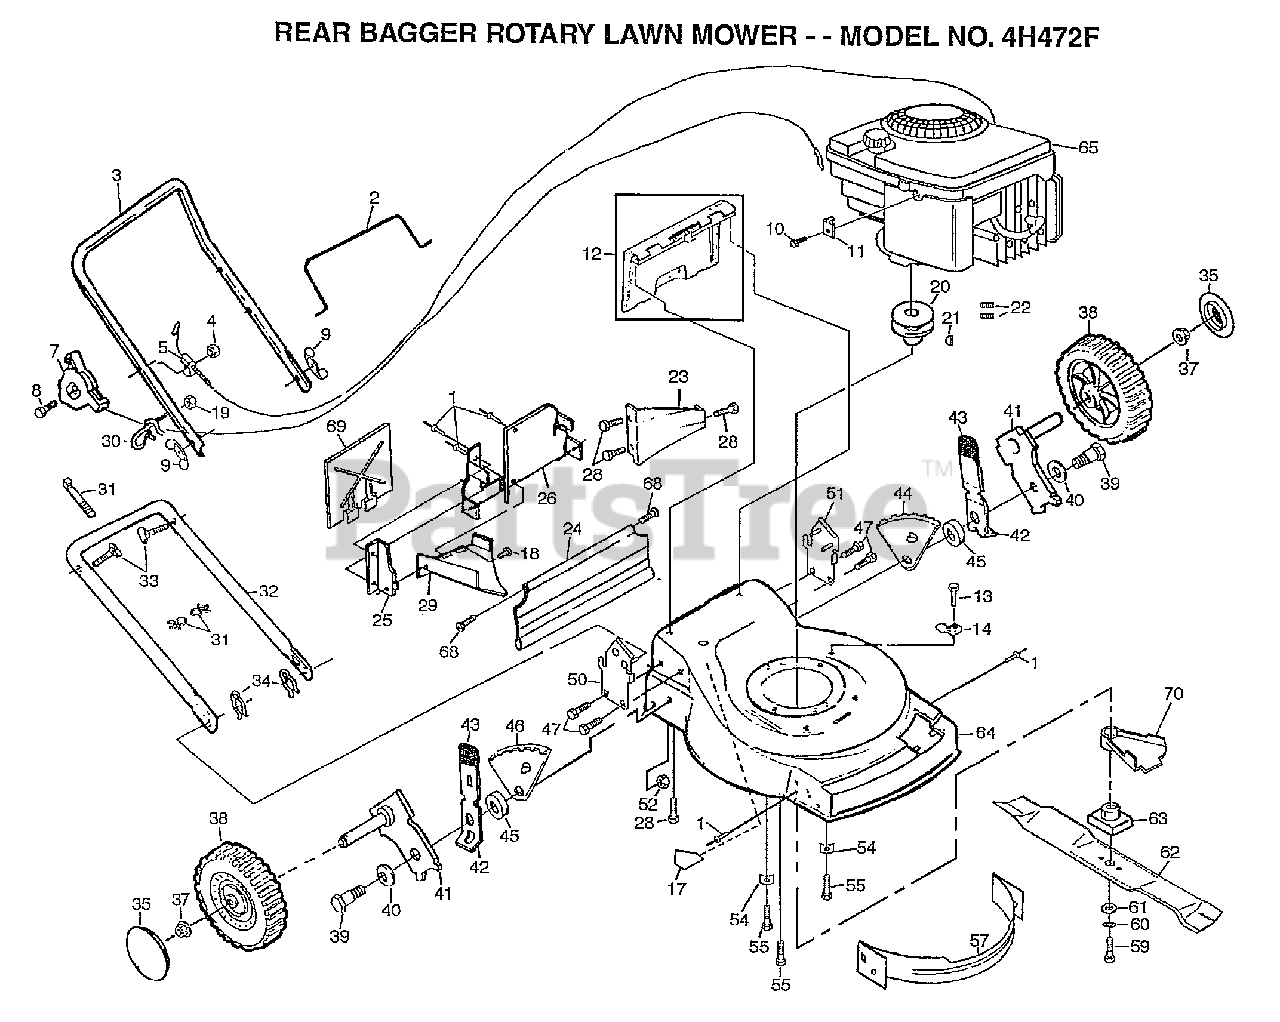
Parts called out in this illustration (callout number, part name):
1	BLIND RIVET
2	BAIL.CNTRL.DLX.ST
5	"CABLE,ENG ZONE CO"
7	"CONTROL, THROTTLE"
8	SCREW.HXHD.WASH.
9	"NUT,WING PM"
10	SCREW PM
11	CABLE CLAMP
12	KIT.DOOR.REAR
13	TAPPING SCREW
14	GUIDE CLIP PM
17	DECAL HYT
18	SCREW.HXTAP.10-24
19	NUT
20	ENGINE.PULLEY.FWG
21	HI PRO KEY PM
22	SCREW
23	REAR BAFFLE
24	SKIRT.REAR.FGD.22
26	PLATE.BACK
28	SCREW
29	DISCHARGE BAFFLE
30	ROPE GUIDE
32	LOWER HANDLE
33	BOLT.HANDLE.LM
34	HAIRPIN COTTER
35	HUB CAP
37	HEX FLANGE LOCKNT
38	WHEEL.8X2.PR.RAD.
39	BOLT SHLD 3/8-16
40	"WASHER, BELLEVIL."
41	ARM.AXLE.ASM.BZP.
42	SPRING SELECTOR
43	KNOB PM
44	BRACKET.ADJ.9.LH
45	SPACER.HEIGHT.ADJ
46	BRACKET.ADJ.9.RH
47	SCREW.HXWS.5/16
50	BRACKET.HDL.RH.
51	BRACKET.HDL.LH.
52	LOCKNUT PM
55	BOLT.ENG.3/8-16
59	SCREW
60	LOCKWASHER
61	"WASHER,HARDEN"
62	"BLADE.MULCH.22"""
63	ADAPTOR.BLADE.LM
64	KIT.HSG.22RD.FWGD
68	HINGE SCREW
69	MULCHER PLATE
